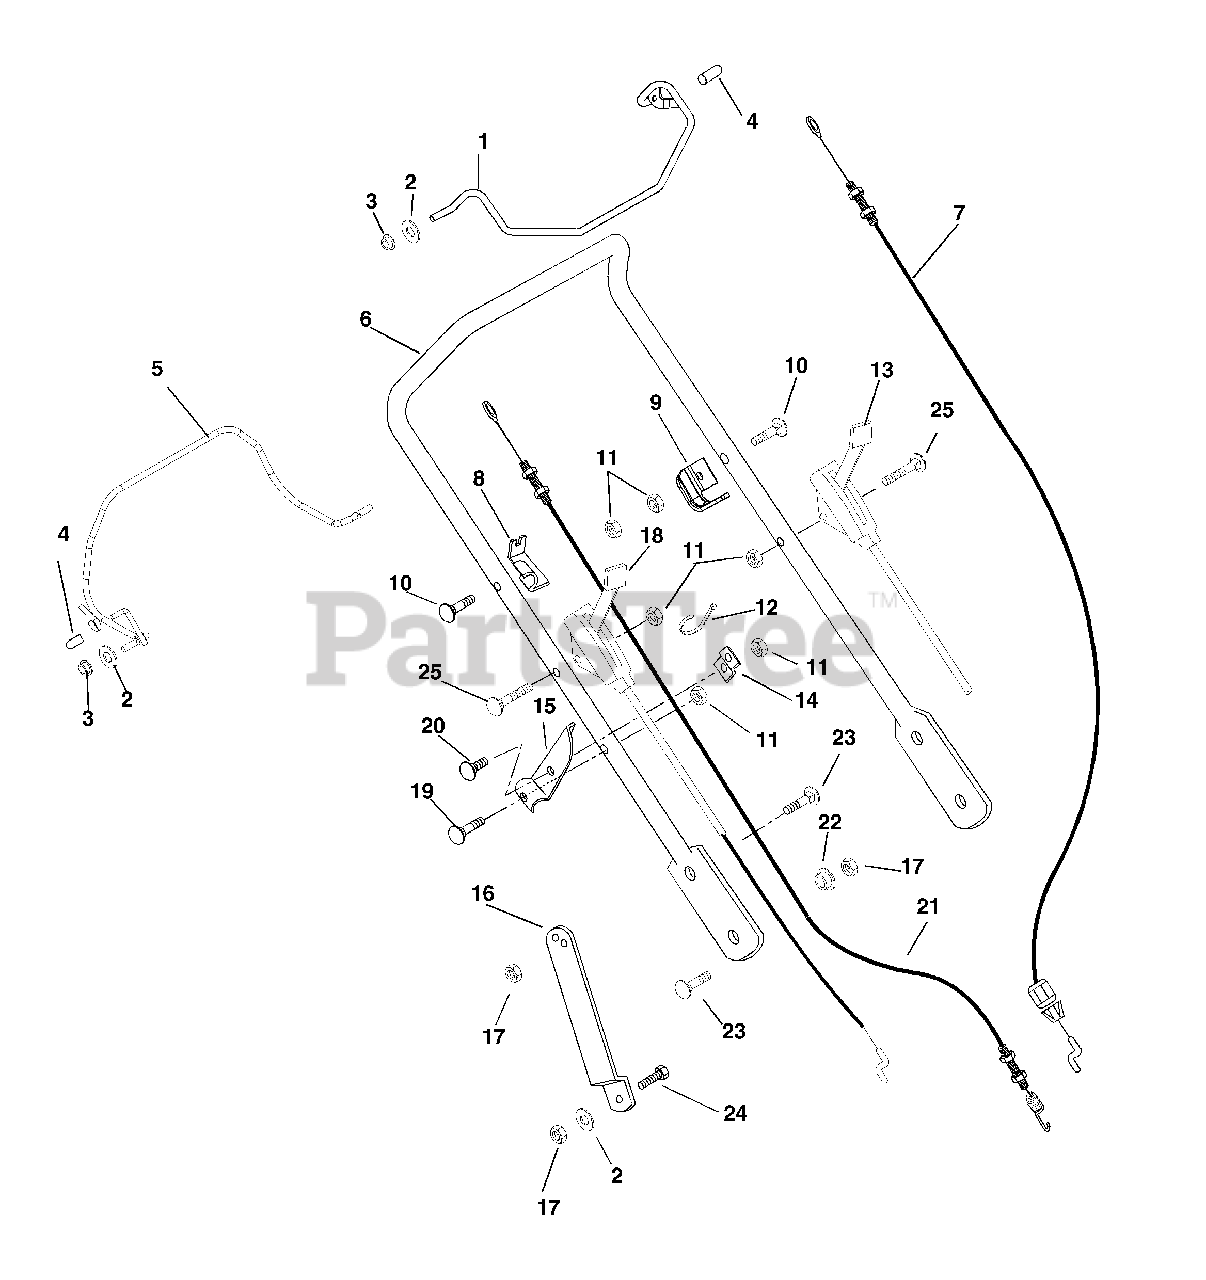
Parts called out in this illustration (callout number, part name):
1	ENGINE BAIL
2	@WSHR-FL-STL.344X.688X.065YWZC
3	BSHG-FLG .325X.444X.440X.560
4	CAP, VINYL, .25 ID
5	BAIL-TRACTION 3 SPD
6	HANDLEBAR
7	ENGINE CABLE
8	CABLE ANCHOR, RH
9	CABLE ANCHOR-LH
10	BLT-RDHDXLSQNK.25-20X1.25 G5ZC
11	@NUT-LK-CTR .25-20 YWZC
12	CABLE TIE LG 5-1/2
13	THROTTLE CABLE
14	BRACE, SPEED CONTROL
15	BRACKET, SPEED CONTROL
16	BRACKET, HANDLEBAR
17	@NUT-LK-CTR .31-18 YWZC
18	CABLE-GEAR SHIFT
19	@BLT-RDHDSQNK .25-20X1.50 G5YZ
20	@BLT-RDHDSQNK .25-20X.50 G5YZ
21	CABLE-TRACTION (SPECIAL)
22	BSHG, FLG .325X.499X.26X.88
23	@BLT-RDHDSQNK .31-18X.75 G5YZ
24	@BLT-HEX .31-18X.75 GR5 YWZC
25	BLT-RDHDSQNK .25-20X1.75 G5YZ
